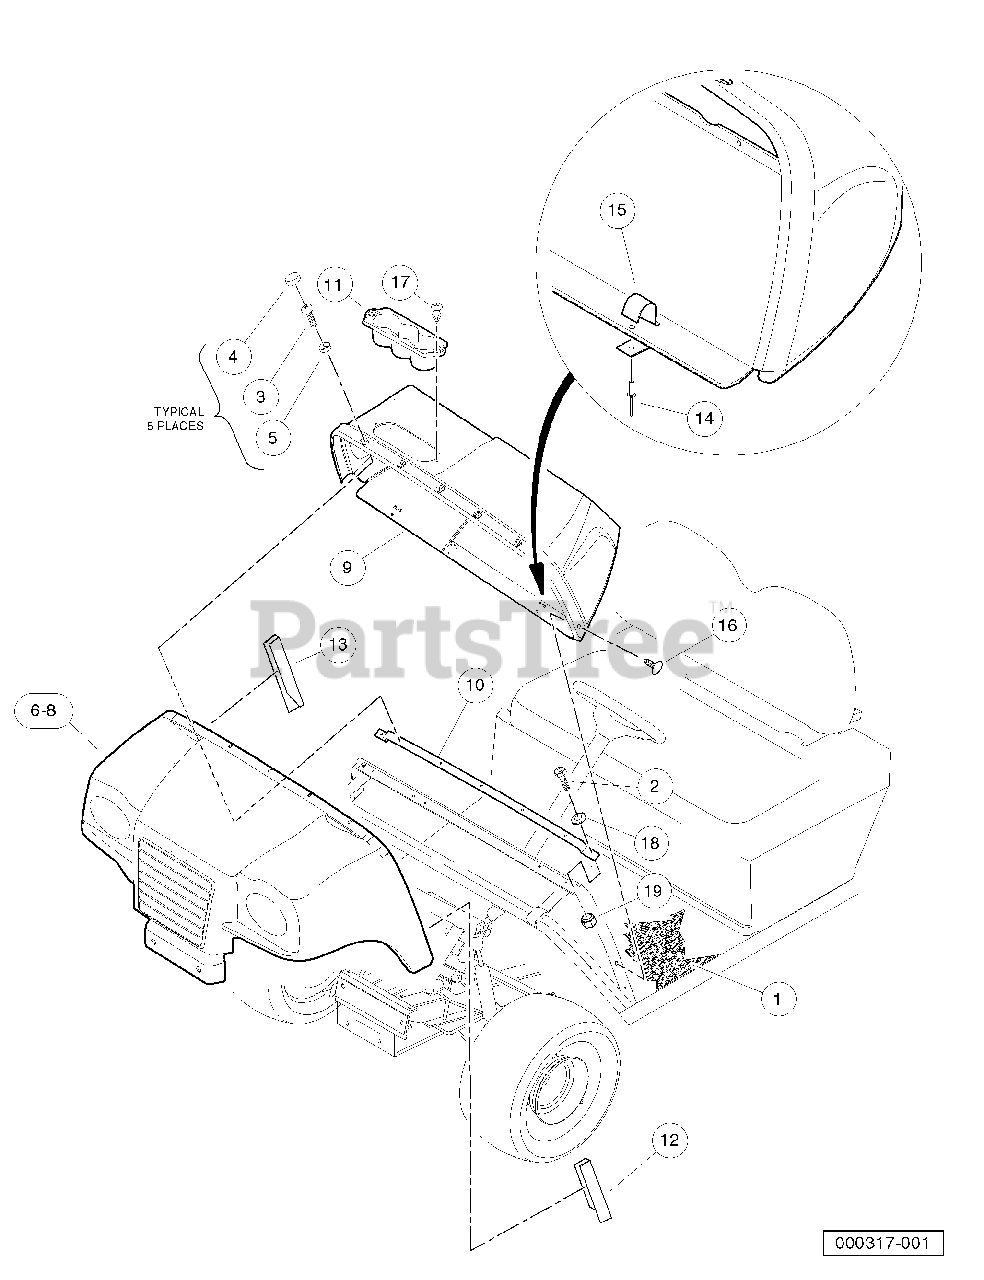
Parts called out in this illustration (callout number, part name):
2	Screw, 1/4-20 X 0.75 Hex-Head Cap
3	Screw, 1/4-20 X .75 Torx Pn Hd
4	Cap, 1/4" Plastic Screw Head
5	Washer, 1/4 Id Scalloped Plast
6	Cowl, Orange
7	Cowl, 4210, Camo
8	Cowl, 4210, Olive Green
10	Support, Upper Cowl
11	Object Holder
12	Cowl Cover, Driver-Side
13	Cowl Cover, Passenger-Side
15	Clip, Dash
16	Push Pin, Black
17	Rivet, Removable, Tuflok 1/4"
18	Washer, 1/4 Type A Narrow Flat
19	Locknut, 1/4-20 Nylon Insert
